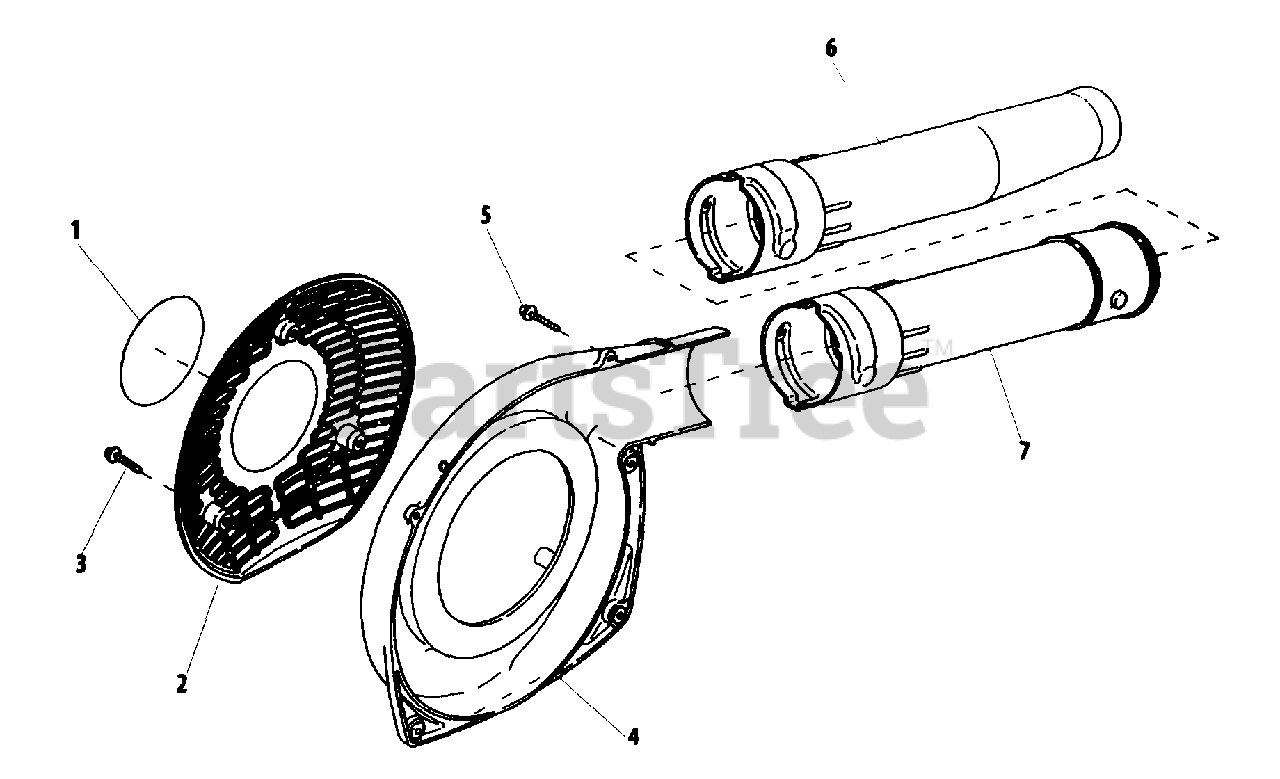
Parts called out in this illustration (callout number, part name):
1	LABEL - MODEL
2	COVER, INTAKE
3	SCREW M5
4	COVER, FAN - LEFT
5	SCREW M5
6	NOZZLE
7	PIPE
